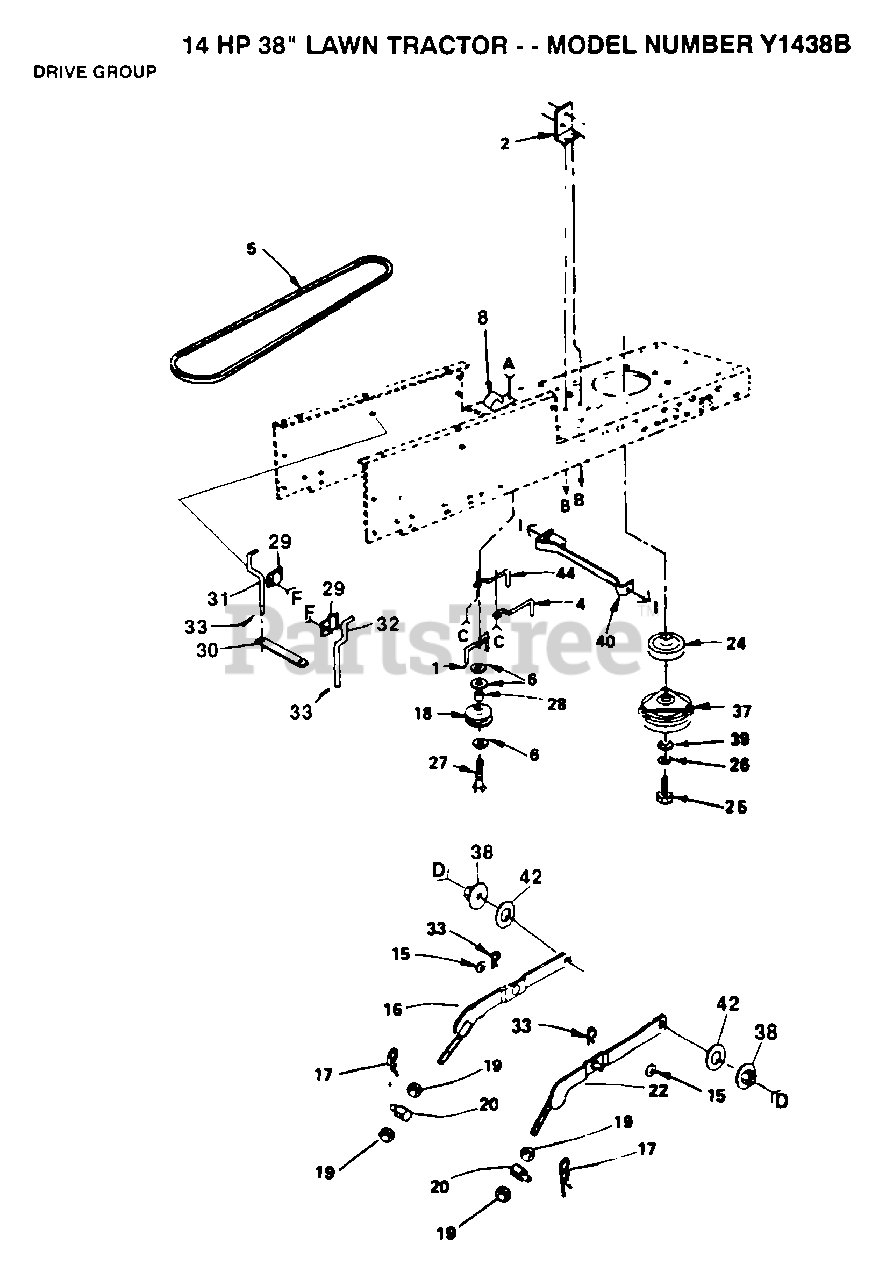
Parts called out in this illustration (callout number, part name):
1	BELT KEEPER LT
2	BRACKET LT
4	"KEEPER,BLT ENG LT"
5	BELT-V.90.0.GD.DR
6	WASHER
8	CLIP T
16	LH SUSP ARM ASM
17	SPRING H
18	PULLEY.IDLER.FLAT
19	NUT
22	RH SUSP ARM ASM
26	LOCKWASHER
27	BOLT
28	SPACER T
29	CLAMP LT
30	STRAP LOCATOR
31	KEEPER BELT LH
32	KEEPER BELTRH
33	SPRING.RETAINER
38	NUT SPECIAL T
39	WASHER
42	WASHER T
44	KEEPER BELT ENGLH
